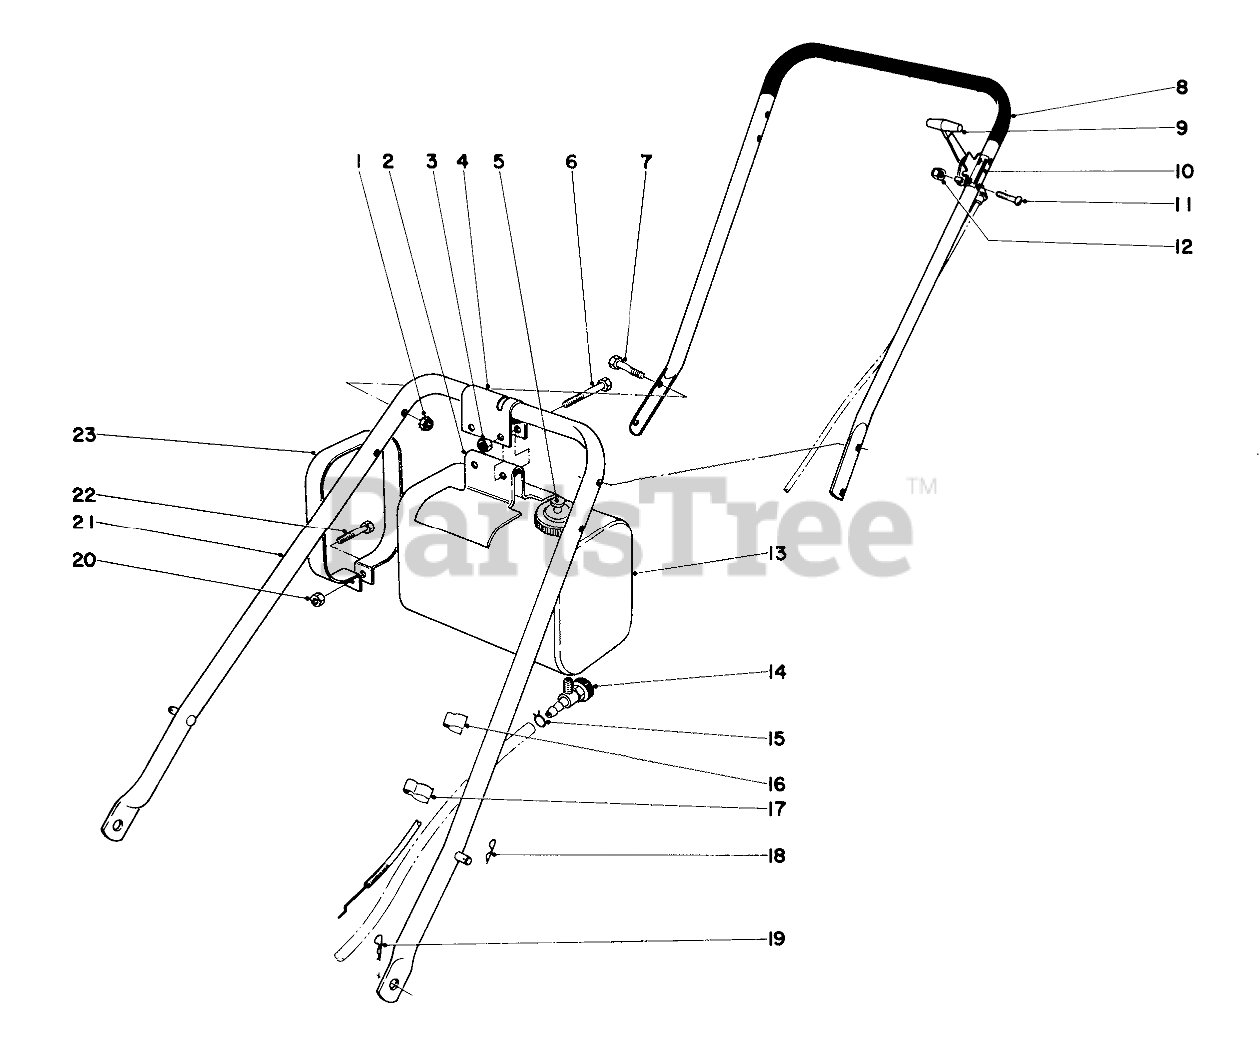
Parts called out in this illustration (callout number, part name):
1	NUT-KEPS
2	FUEL TANK BRACKET
3	Nut
4	Clamp, Fuel Tank
6	SCREW-HH
7	SCREW-HH
8	Upper Handle Assembly
9	Throttle Control
10	Decal
11	10-24X1-1/8 RND HD MS
12	NUT-LOCK, NI
13	Tank
14	.125 ID SHUTOFF VALVE
15	Clamp
16	Clamp
17	CLAMP
18	PIN-COTTER
19	PIN-COTTER, HAIR
20	Nut
21	Lower Handle
22	SCREW-HH
23	TANK STRAP
